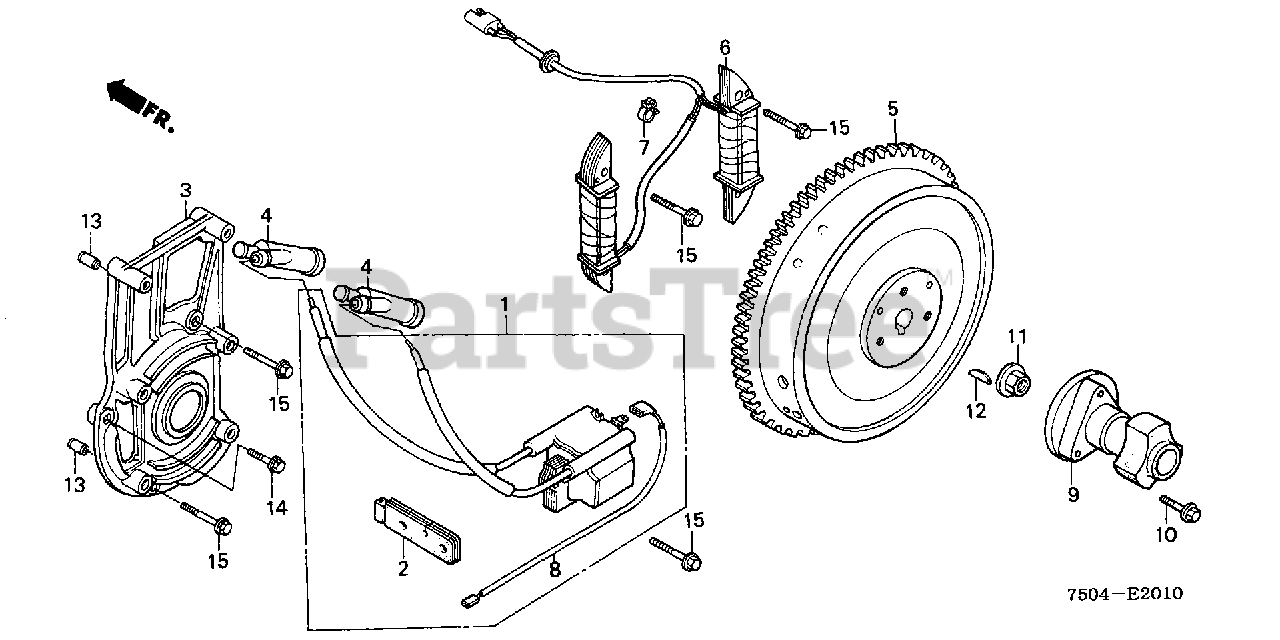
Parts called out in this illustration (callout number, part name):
1	COIL ASSY., IGNITION
2	GROMMET, IGNITION WIRE
3	STAY, IGNITION SYSTEM
4	CAP ASSY., NOISE SUPPRESSOR
6	COIL ASSY., CHARGE (10A)
7	CLIP, IGNITION WIRE (8MM)
7	CLIP, HARNESS
8	WIRE, ENGINE STOP
9	DAMPER A, PROPELLER SHAFT
10	BOLT, UBS (8X33)
11	NUT, SPECIAL (16MM)
12	KEY, SPECIAL WOODRUFF (25X18)
13	PIN A, DOWEL (8X10)
14	BOLT, FLANGE (6X22)
15	BOLT, FLANGE (6X32)
